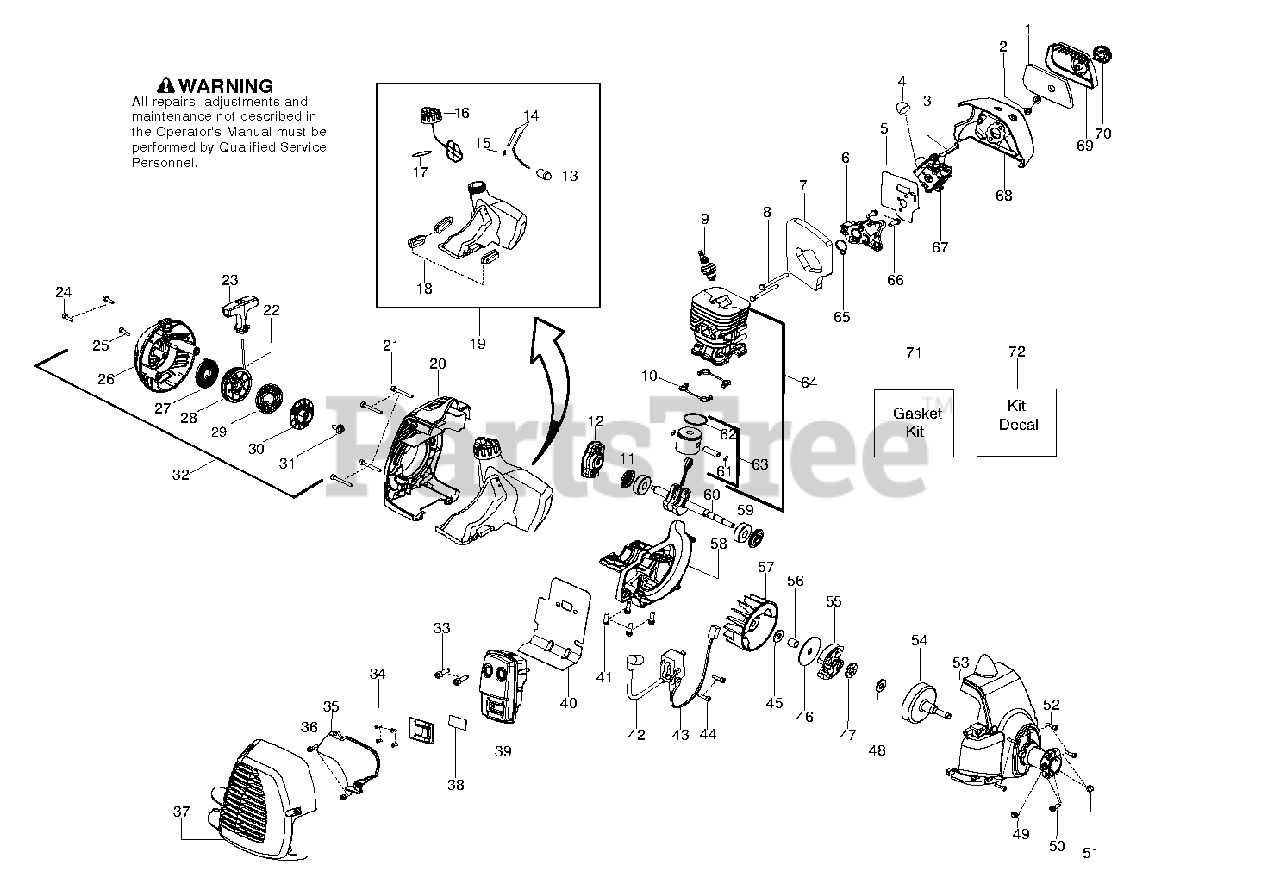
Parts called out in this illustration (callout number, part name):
1	FILTER AIRBOX
3	CHOKE LEVER
4	PURGE BULB ZAMA
5	KIT GASKET CARB 28CC
6	CARB ADAPTOR
7	KIT GASKET 28CC
8	BOLT CARB ADAPTOR
9	Spark Plug, BPMR6A BLYB
10	KIT GASKET 28CC
11	KIT GASKET 28CC
12	STARTER PAWL BRIDGE
13	FUEL PICK-UP ASSY
14	KIT-LINE(FUEL)
15	FUEL LINE FITTING
16	ASSY-CAP W/RETAINER
17	KIT GASKET 28CC
18	ISOLATOR FUEL TANK
19	KIT FUEL TANK HVA
20	REAR SHROUD ORANGE
22	KIT ROPE
23	STARTER HANDLE
24	SCREW M5-0.8X30MM
25	SCREW M4 X 1.75 PT 16MM
26	KIT STARTER HSG HVA 128
27	KIT STARTER SPRING
28	KIT STARTER PULLEY
29	SPRING - DRIVER
30	DRIVER PULLEY
32	ASSY STARTER HSG HVA
33	BOLT MUFFLER
34	SCREW-6-19X5/16PLAST PA
35	SHIELD HEAT
36	SCREW M4 X 1.75 PT 16MM
37	KIT MUFFLER GUARD HVA
38	KIT SPARK ARRESTOR SCREEN
39	KIT MUFFLER W/CATALYST
40	KIT GASKET 28CC
41	SCREW-M5-0.8 X 25MM(TAP)
42	IGNITION MODULE MBU-7
43	ASSY MODULE LEAD WIRE
44	SCREW M4 X .70 TT 16MM
45	WASHER CLUTCH
46	WASHER-CLUTCH
47	BEARING THRUST
48	WASHER THRUST
49	SCREW-10-14 X 1/2 PLASTITE
50	SCREW-10-24 X 1" (UNC)
51	LOCKNUT-HEX 10-24
52	SCREW M4 X .70 TT 16MM
53	ASSY FAN HOUSING HVA 1"
54	ASSY-CLUTCH DRUM
55	ASSEMBLY CLUTCH
56	SPACER FLYWHEEL
58	CRANKCASE CAST LE28
59	BEARING RADIAL BALL (6201)
60	ASSY CRANKSHAFT
61	WRIST PIN RET.
62	RING PISTON
63	KIT - PISTON
64	KIT PISTON CYL
65	KIT GASKET 28CC
66	SCREW-M5-0.8 X 25MM(TAP)
67	KIT CARB
68	AIRBOX HVA 128 HUSKY GRAY
69	COVER-AIR BOX
70	KNOB ASSY AIRBOX COVER
71	KIT GASKET 28CC
72	KIT DECAL
